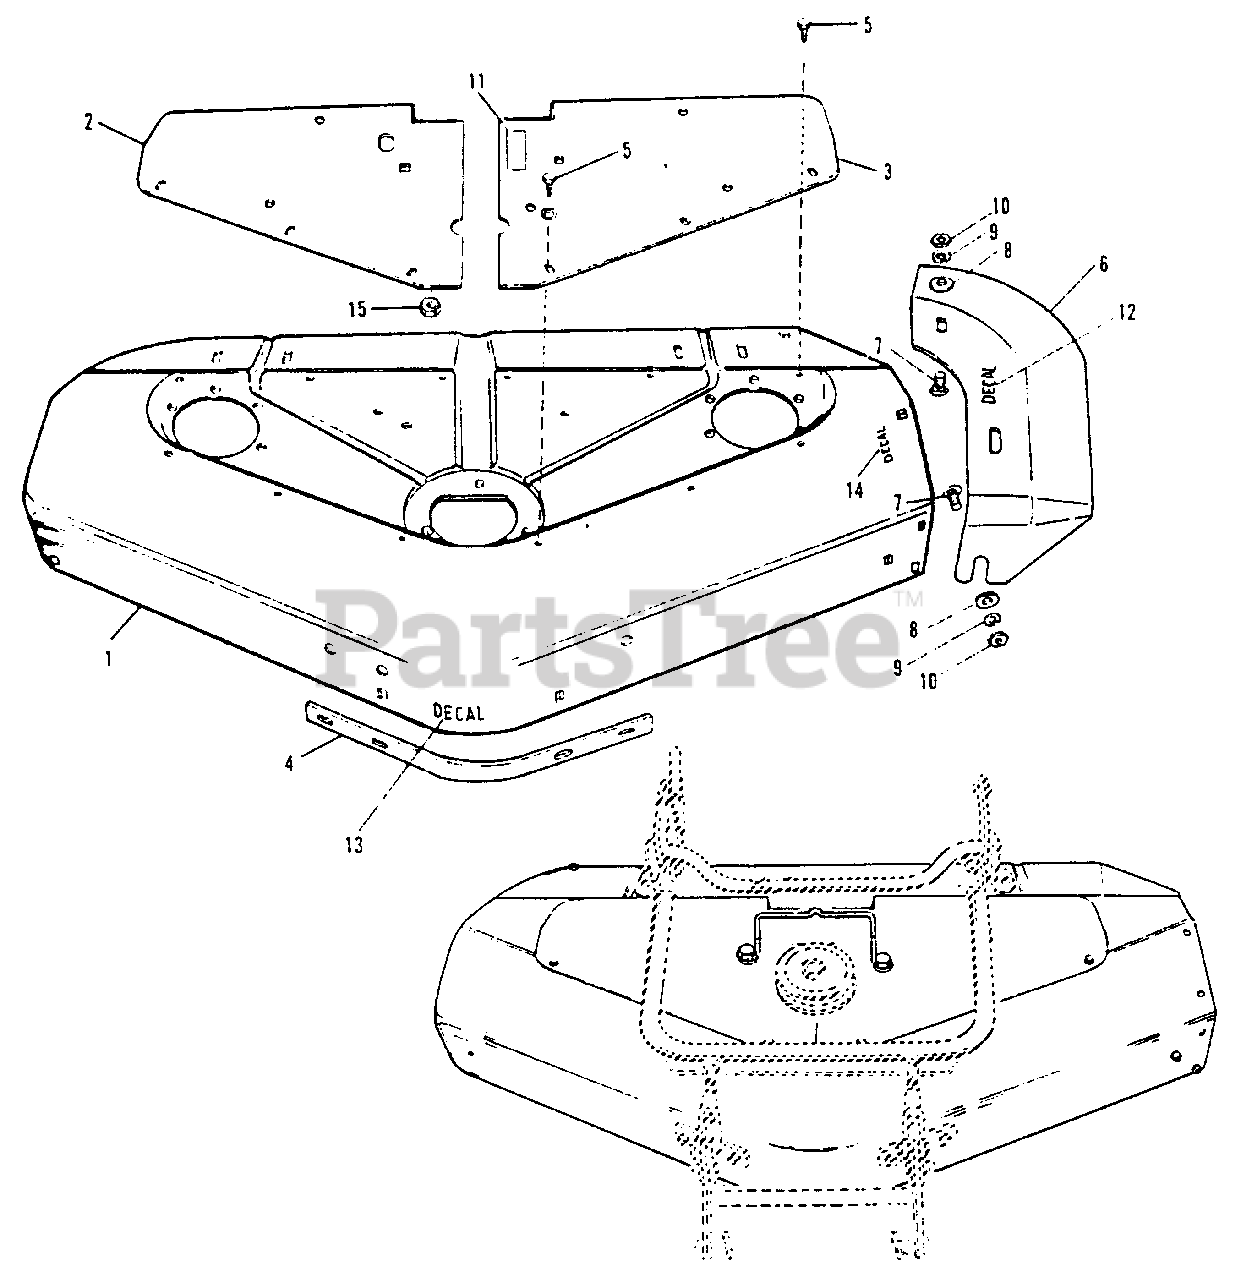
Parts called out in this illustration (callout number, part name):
1	Mower Housing
2	Cover, R.H.
3	Cover, L.H.
4	Bar, Reinforcing
5	Screw, Taptite, 1/4"-20 x 3/8" lg.
6	Deflector
7	Carriage Bolt, 3/8"-16 x 3/4" lg.
8	Washer Special
9	Washer Lock, 3/8"
10	Hex Nut, Full, 3/8"-16
11	Film Belt Instructions
14	Film, Safety
15	Nut Retainer
